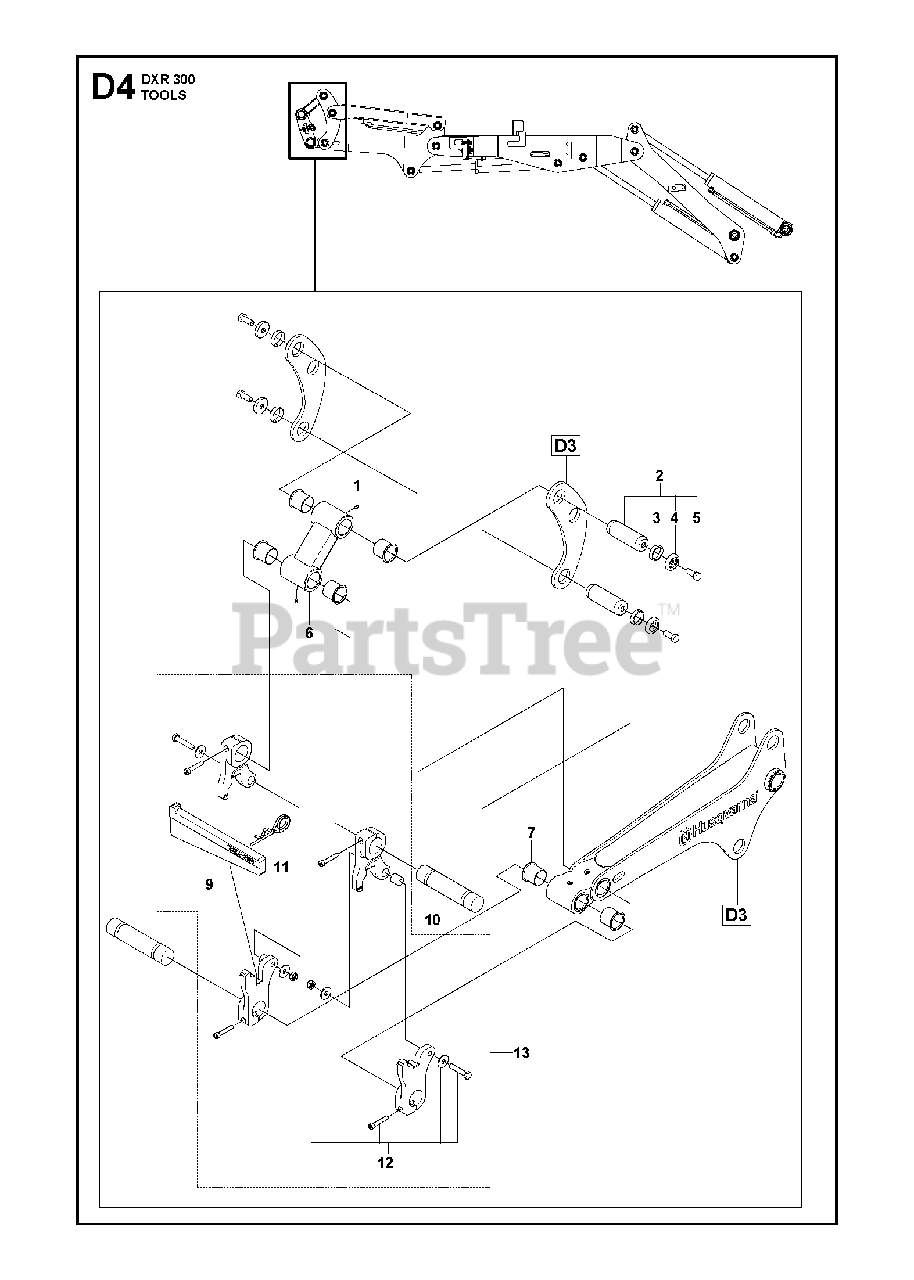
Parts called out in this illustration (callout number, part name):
9	WEDGEvalid for old tool hitch
10	SHAFTvalid for old tool hitch
11	CLIPvalid for old tool hitch
12	KITvalid for old tool hitch
13	HITCHvalid for old tool hitch
